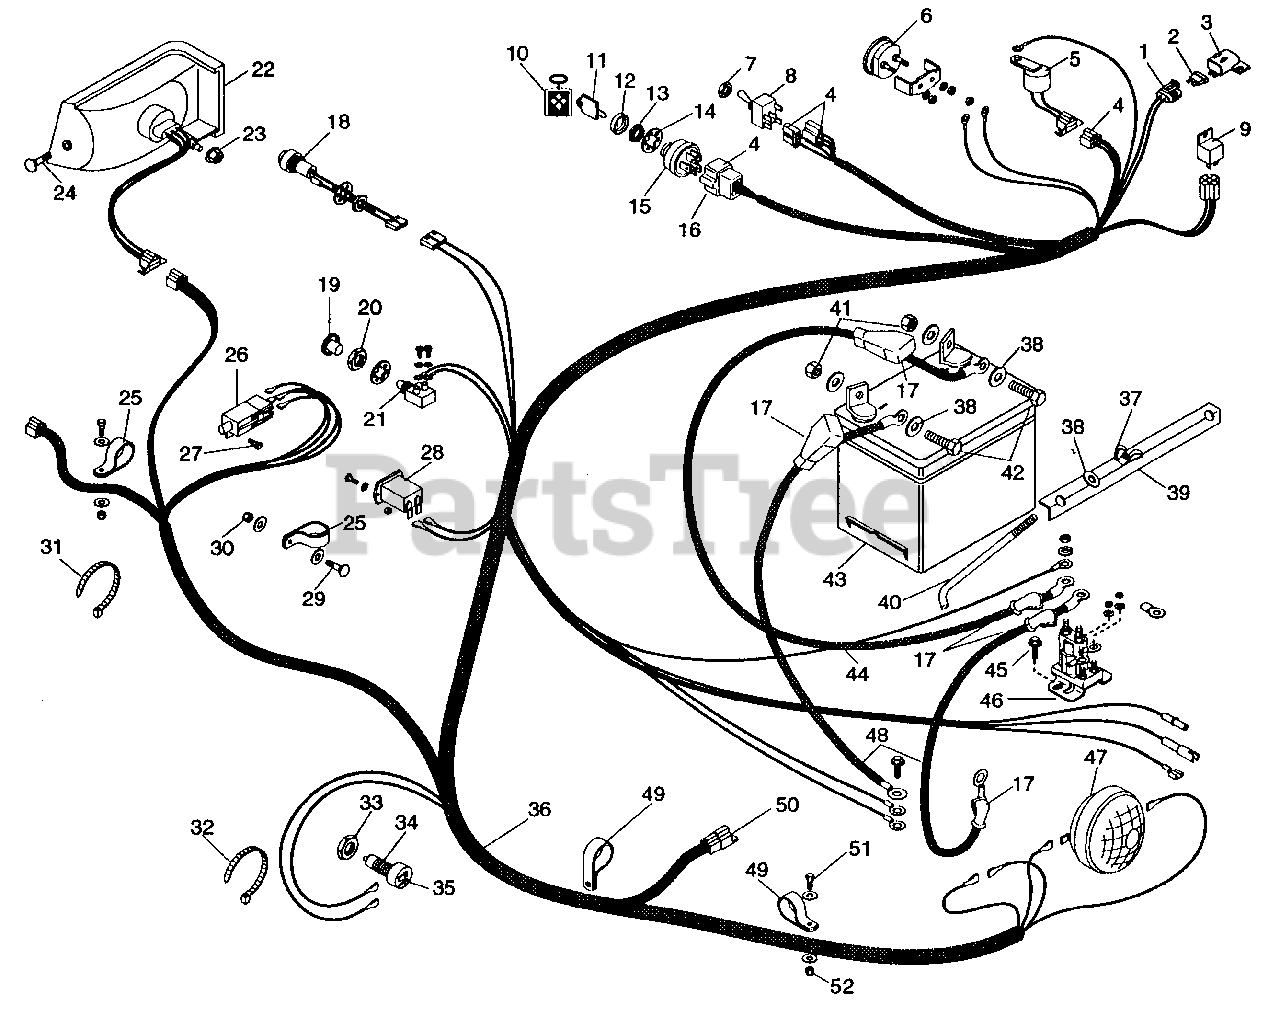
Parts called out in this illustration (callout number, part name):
1	Term., For 10-12 Ga Wire
2	Fuse, 25 AMP
3	Cvr
4	Terminal
6	Gauge-Ammeter
7	Nut .50-27
8	Switch Assembly
9	Relay
10	Key Chain
11	Ignition Switch Key
12	Cap-Ignition Switch
13	Nut-Panel .562-24 Greco
14	Wshr-Lock Int .563 x .040 Pl
15	Ignition Switch
16	Connector
17	Boot, Insulator
18	Light Indicator
19	Knob, Light Switch
20	Nut-Jam .375-32
21	Light Switch
22	Right Tail Light
22	Left Tail Light
23	Palnut - .25
24	Scr-Tap 10-12 x .50 Ph Cr A
25	Clamp
26	Switch Double Pole
27	Scr-Tap 12-24 x .50 Hwh Pl
28	Hour Meter
29	Blt-Carriage .31-18 x 1.0
30	Blt-Rdhdsqnk .31-18 x .885 Pl Bl
31	Tie Wrap, Black
32	Clamp, Universal
33	Nut .625-32 Pl
34	Boot
35	Safety Switch
36	Wire Harness
37	Nut-Wing .250-20
38	Wshr-Fl-Stl .281 x .625 x .065
39	Hold Down
40	Tie Down
41	Nut-Lk-Nyl .250-20 Pl
42	Blt-Hex .25-20 x .75 Pl Gr 5
43	Battery
44	Cable, Starter
45	Scr-Tap .25-20 x .50 Hxslhdpl
46	Solenoid
47	Head Light
48	Cable, Ground
49	Clamp, Cushioned Steel
50	Connector
51	Blt-Hex .380-16 x .875
52	Nut-Lk-Nyl .375-16 Pl
